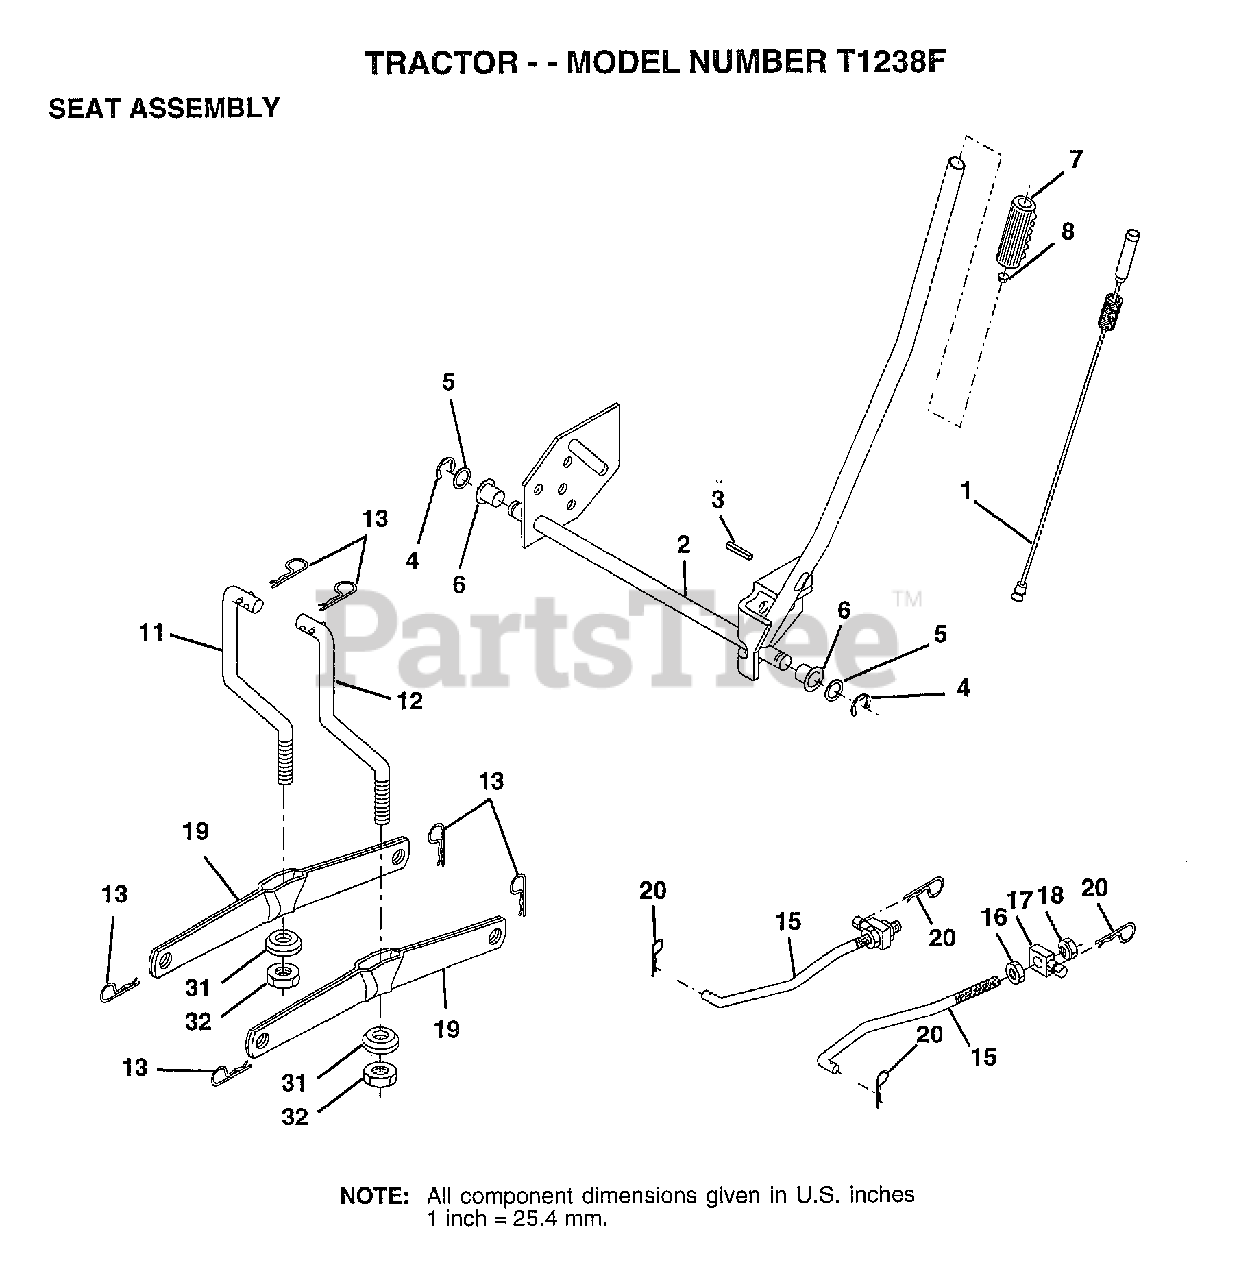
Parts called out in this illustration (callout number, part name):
1	WIRE ASM W.SPRING
2	SHAFT ASM.LIFT
3	PIN-GROOVE LT
5	WASHER
6	NYLON BEARING
7	GRIP
15	LINK.FRONT
16	NUT
17	TRUNION
18	NUT.LK.W/WSH.1/2.
19	ARM SUSP REAR
20	RETAINER SPRING
31	BEARING PVT LH
32	NUT.CROWNLOCK.3/8
